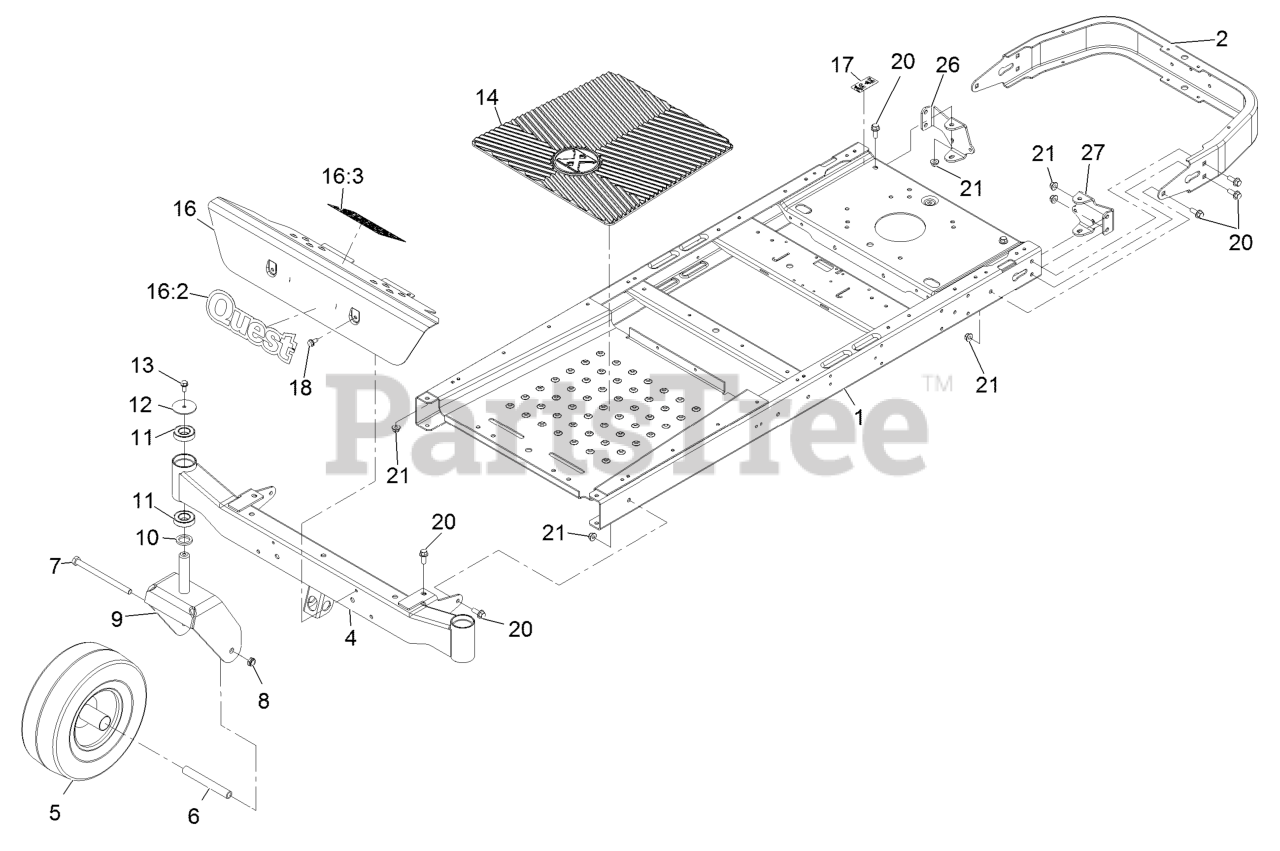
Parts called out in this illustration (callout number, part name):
2	BUMPER-REAR (WIDE)
4	AXLE-FRONT, WIDE
5	13 INCH WHEEL AND TIRE AS
6	SPANNER
7	WASHER-LOCK
8	NUT-HEX
9	FORK-CASTER
10	WASHER-THRUST
11	BEARING-BALL
13	SCREW-HHF
14	MAT-FLOOR
16	FOOTREST SERVICE ASM
17	DECAL-BYPASS
18	Screw-HWH 5/16-18 X 3/4 Tf
20	SCREW-HHF 3/8-16 X 1
21	NUT-HF, NI
26	MOUNT-HYDRO, REAR (RH)
27	MOUNT-HYDRO, REAR (LH)
